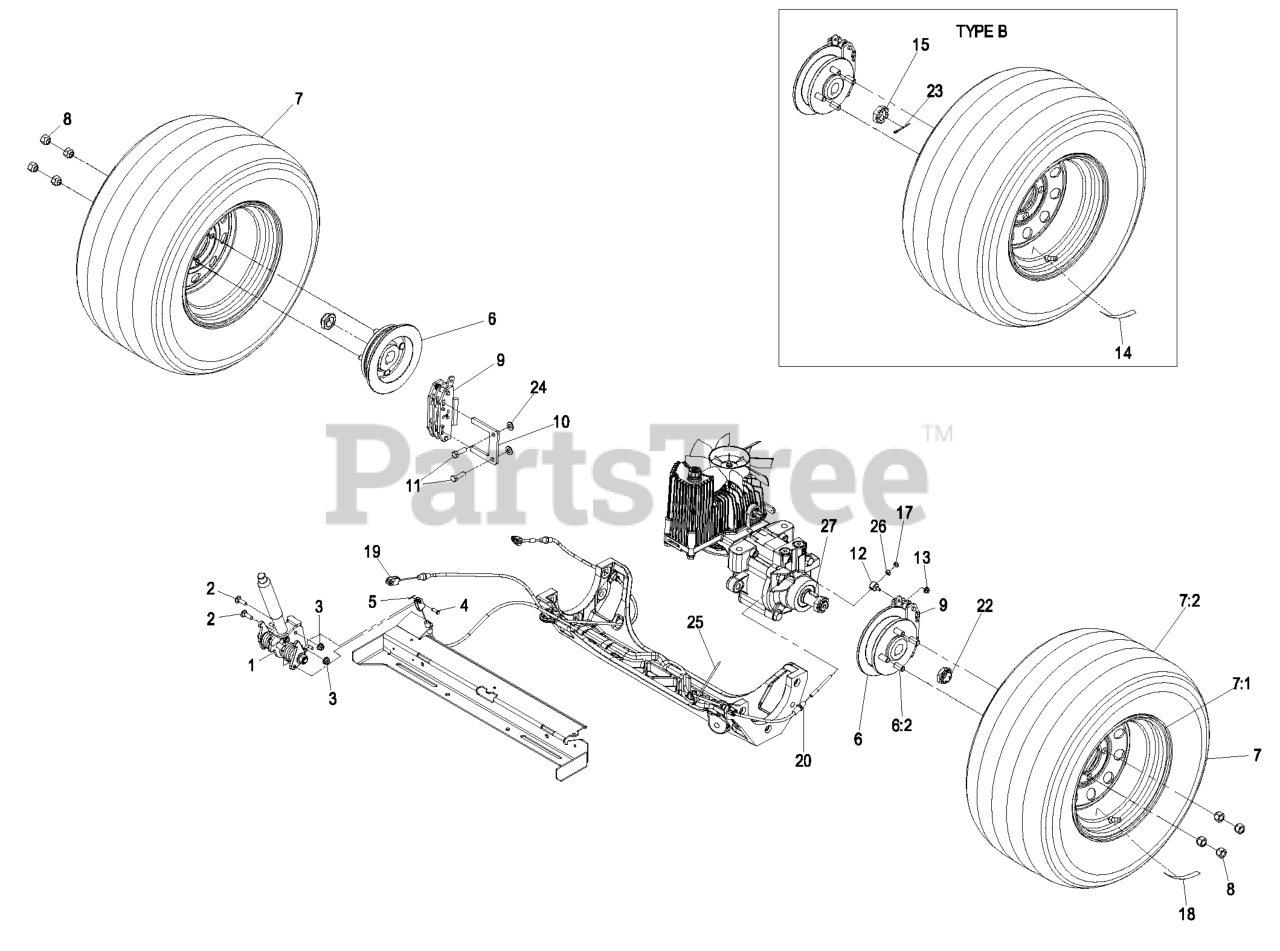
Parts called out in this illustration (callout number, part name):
1	BRAKE HANDLE ASM
2	BOLT-CARR
3	NUT-HF, NI
4	PIN-CLEVIS
5	PIN-COTTER
6	WHEEL HUB ASM
6:2	STUD-WHEEL
7	WHEEL AND TIRE ASM
7:1	RIM ASM
7:2	TIRE
8	NUT-LUG
9	CALIPER-BRAKE
10	PLATE-MOUNT, BRAKE
11	SCREW-LOCK, PATCH
14	DECAL-HUB, WHEEL
17	NUT-LOCK, NI
23	PIN-COTTER
24	WASHER-FLAT
25	TIE-CABLE
26	NUT-HEX
27	KEY-WOODRUFF
